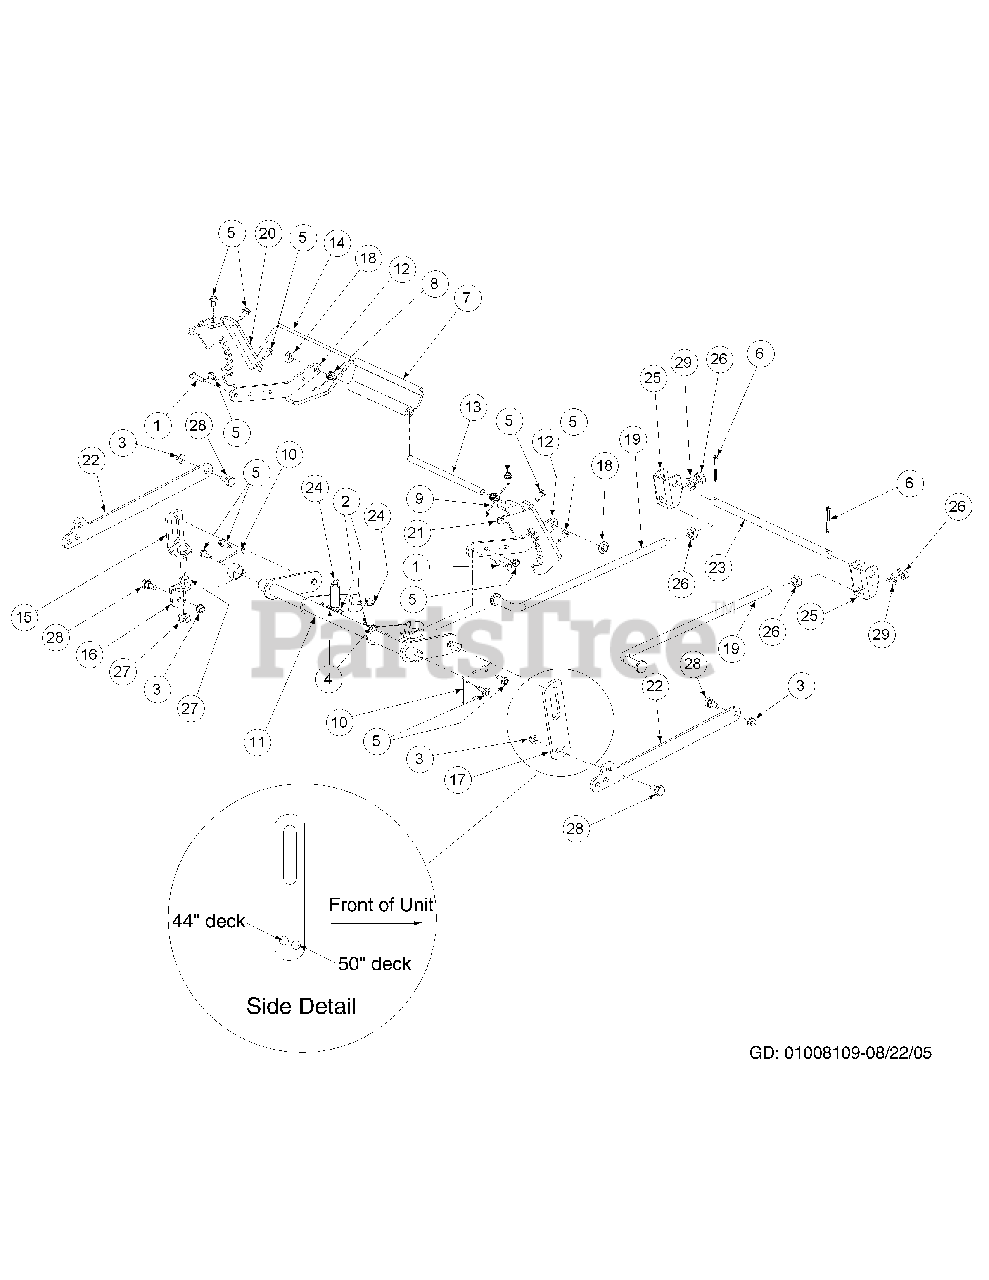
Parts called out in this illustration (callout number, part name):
1	Hex Cap Screw, 5/16-18 x 1-1/2
2	Nut, 5/16-18, Center Lock
3	Nut, 3/8-16, Hex Flange Lock
4	Hex Nut, 5/16-18
5	Self Tapping Screw, 5/16-18 x 3/4
6	Cotter Pin, 3/16 x 1-1
7	Deck Lift Handle
8	Deck Lift Spring, Left Hand
9	Deck Lift Spring, Right Hand
10	Lift Hub Assembly
11	Lift Shaft Assembly
12	Handle Lift Arm
13	Lift Handle Rod
14	Lift Rod Index
15	Upper Link Lift Assembly, Left Hand
16	Lower Lift Bracket, Left Hand
17	Link Lift Plate, Right Hand
18	Cap Lift Push Nut
19	Front Lift Rod
20	Lift Index Weldment, Left Hand
23	Front Lift Rod
24	Lift Spring
25	Front Lift Bracket
26	Jam Nut, 5/8-11
27	Jam Nut, 1/2-20
28	Shoulder Screw, 3/8-16, .56 x .27
29	Lock Washer, 5/8
